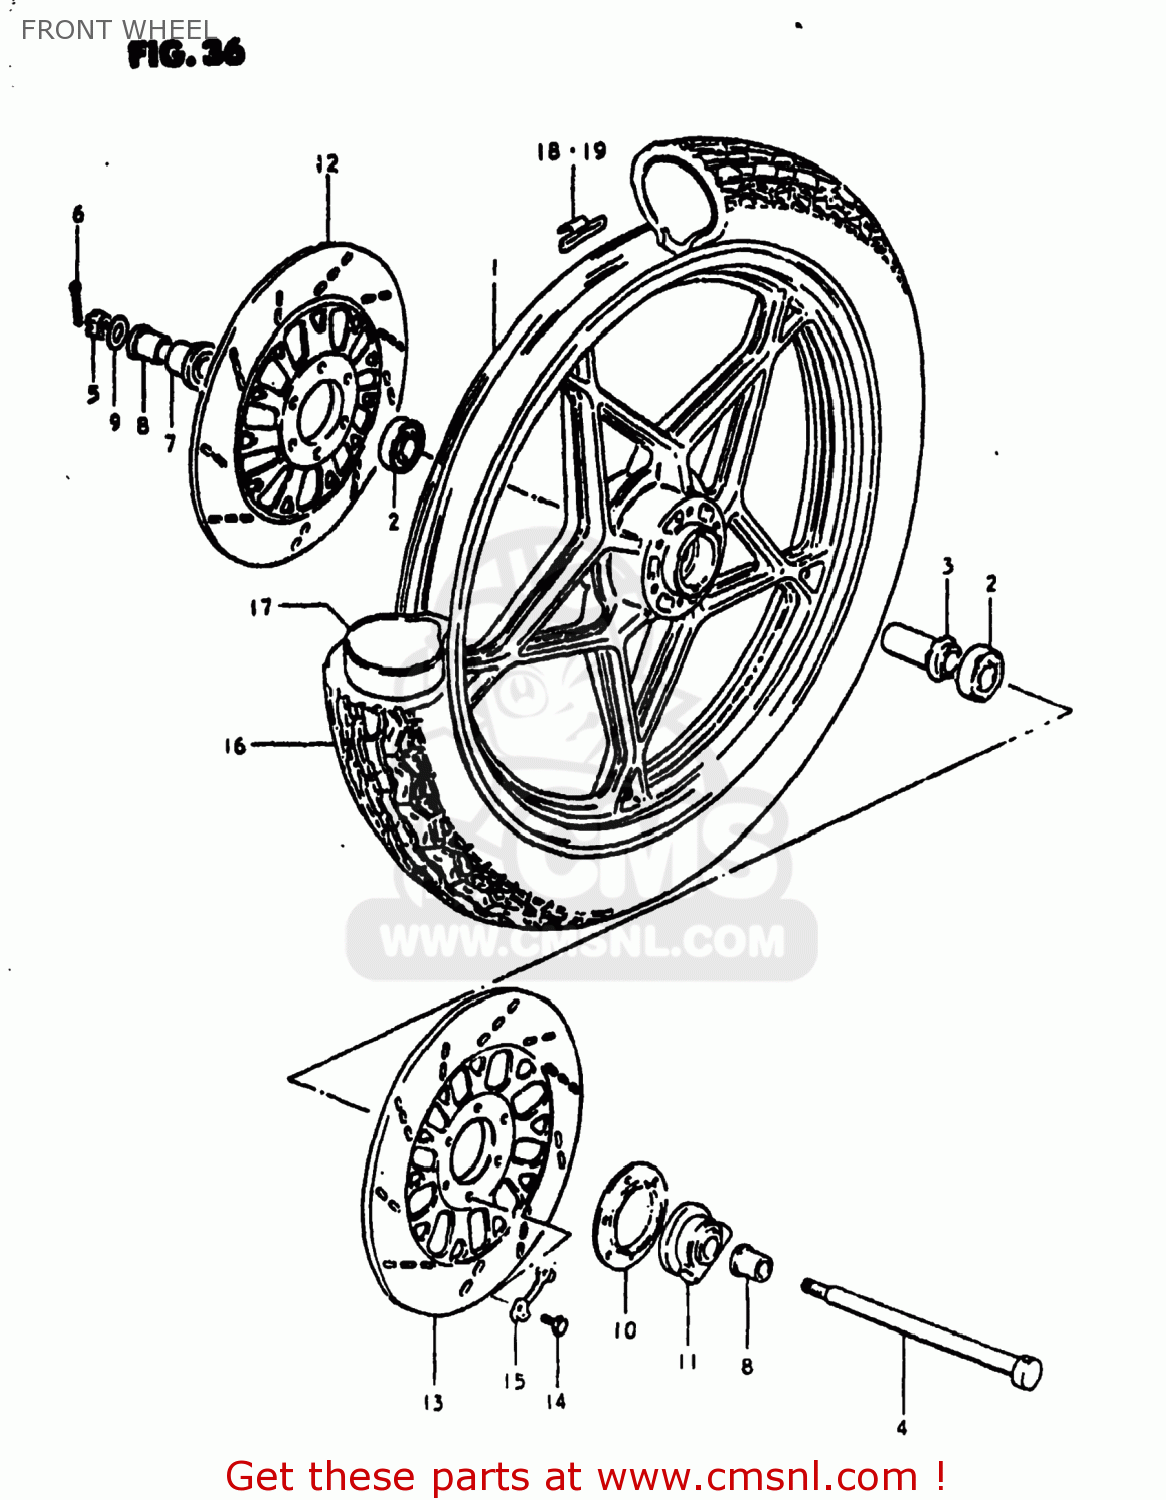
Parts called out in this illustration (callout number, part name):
1	WHEEL, FRONT
2	BEARING
3	SPACER,FR HUB BEARING
4	AXLE,FR
5	NUT 12MM
6	COTTER PIN
7	SPACER,FR AXLE,R
8	SPACER,FR AXLE,L
9	WASHER
10	DUST SEAL,SPEEDOMETER GEAR BOX
11	BOX ASSEMBLY,SPEEDOMETER GEAR
12	DISC,FR BRAKE,R
13	DISC,FR BRAKE,L
14	BOLT(8X25)
15	WASHER
16	TIRE,FRONT
17	TUBE,INNER
18	BALANCER,WHEEL
19	BALANCER,WHEEL
